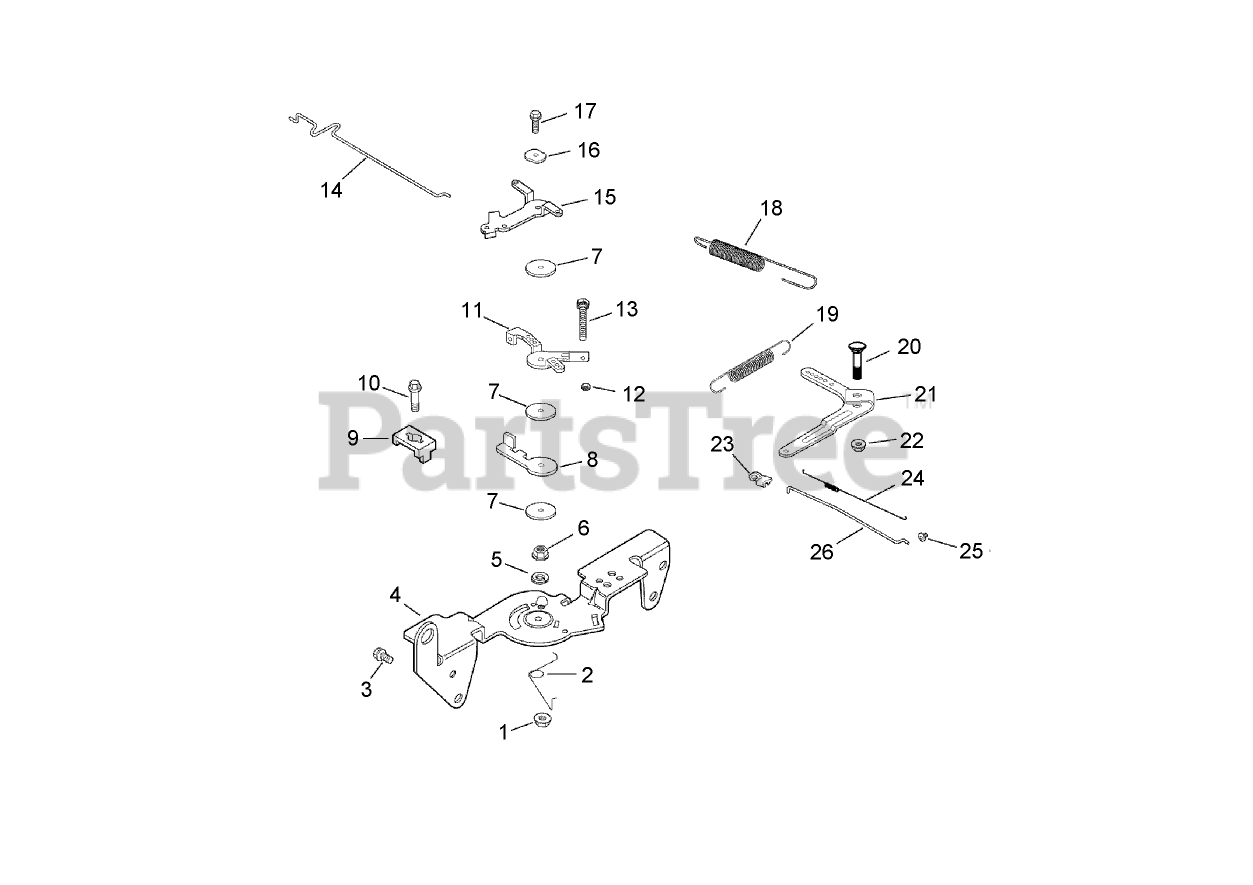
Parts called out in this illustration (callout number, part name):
1	NUT-LOCK (M5X.8)
2	SPRING-RETURN, CHOKE
3	SCREW-FLANGE, THREAD FORMING (M6X1.0X16)
4	Bracket-Control
5	Washer-Lock (.25)
6	Nut-HF (M5x0.8)
7	WASHER-FLAT (5.5MM)
8	Lever-Actuator, Throttle
9	CLAMP-CABLE
10	SCREW-FLANGE, THREAD FORMING (M5X0.8X16)
11	Lever-Control, Throttle
12	NUT (M4X0.7)
13	Screw (M4x0.7x30)
14	Linkage-Choke
15	LEVER-CHOKE
16	WASHER-SPRING (1/4)
17	SCREW-FLANGE, THREAD FORMING (M5X.8X20)
18	Spring-Limiter, Throttle
19	Spring-Governor
20	BOLT-SQ NECK, RD HD (M6X1.0X25)
21	Lever-Governor
22	NUT-FLANGE (M6X1.0)
23	BUSHING-RETAINING, LINKAGE
24	SPRING-LINKAGE
25	BUSHING-LINKAGE, THROTTLE
26	Linkage-Throttle
